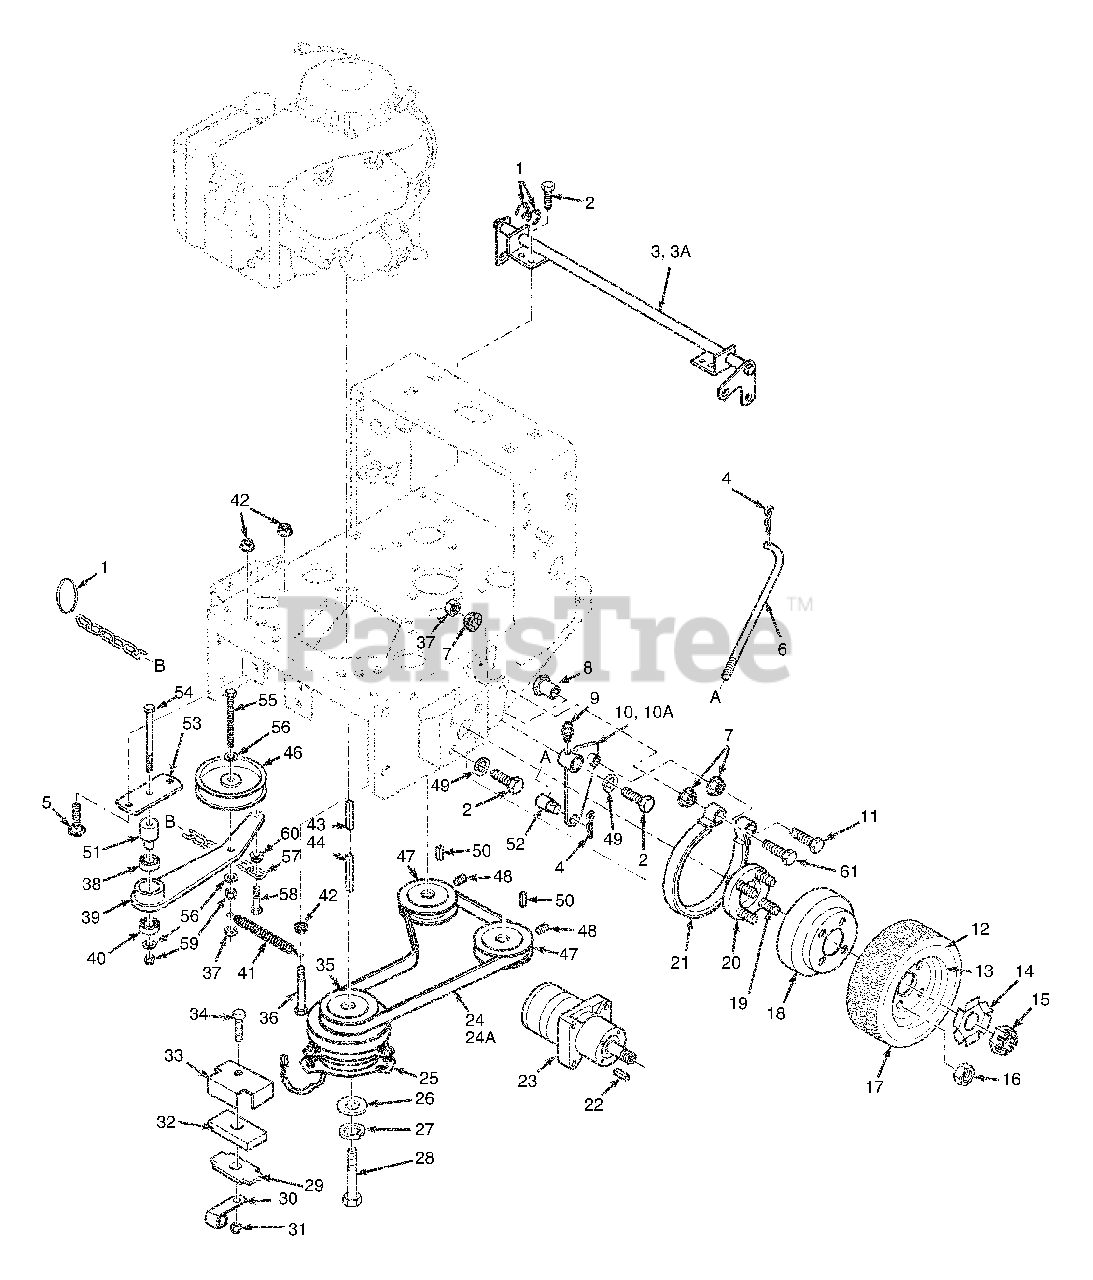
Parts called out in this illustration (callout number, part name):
1	Ring, Split
3	Brake Shaft Assembly Weldment (16" Small Frame)
4	Hair Pin Cotter, .094 x 1.62
5	Carrage Bolt, 5/16-18 x .75"
6	Rod, Brake Lower
7	Nut, 3/8-16 Serr. Flange
8	Bushing, Brake
9	Grease Fitting
10	Brake Actuator Wlmt., LH
10A	Brake Actuator Wlmt., RH
11	Bolt, 3/8-16 x 2-1/4"
12	Tire, 16 x 6.50, 4 ply
13	Rim Assy
14	Lock Washer, Wheel Motor
15	Hex Castle Nut, 3/4-28 UNEF
16	Nut, Lug
17	Wheel Assy.,
18	Brake Drum
19	1/2-20 Serrated Bolt
20	Hub, Wheel
21	Brake Band, 7.5"
22	Key, 3/16 X .75 Woodruff
23	Wheel Motor
24	Belt, Pump Drive (16" Small Frame)
25	Electric Clutch
26	Flat Washer .469 x 1.75 x .25
27	Lock Washer, 7/16
28	Hex Head Bolt, 7/16-20 x 2-3/4"
29	Plate, Backing
31	Nut, 5/16-18 Elastic Stop
32	Rubber Pad, Clutch Stop
33	Retainer, Clutch Stop
34	Hex Head Bolt, 5/16-18 x 1.75"
35	Pulley, Pump Drive Engine
36	Hex Head Bolt, 5/16-18 x 2.75"
37	Nut, 3/8-16 Center Lock
38	Ball Bearings
39	Idler Arm Weldment, Pump
40	Ball Bearings
41	Spring, Pump Belt Idler
42	Nut, 5/16-18 Serr. Flange
43	Key, 1/4x1/4 x 1.00" Clutch Mtg.
44	Key, 1/4x1/4 x 2.75" Pulley Mtg.
45	Flat Washer, 3/8
46	Pulley, Idler 4.5"
47	Pulley, Pump Shaft
48	Setscrew, 5/16-18 x 3/8"
49	Lockwasher, 3/8
50	Key, 5.0 x 5.0 x 25mm
51	Pivot, Idler (Long)
52	Swivel Joint
53	Base, Idler Pivot
54	Bolt, Hex Head 3/8-16 x 3"
55	Bolt, Hex Head 3/8-16 x 2.75"
56	Flatwasher 3/8"
57	Chain
58	Bolt, Hex Head 1/4-20 x 1.25"
59	Nut, Hex Elastic Stop 3/8-16
60	Nut, Serrated Flange 1/4-20
61	Bolt, Hex Head 3/8-16 x 2.63"
